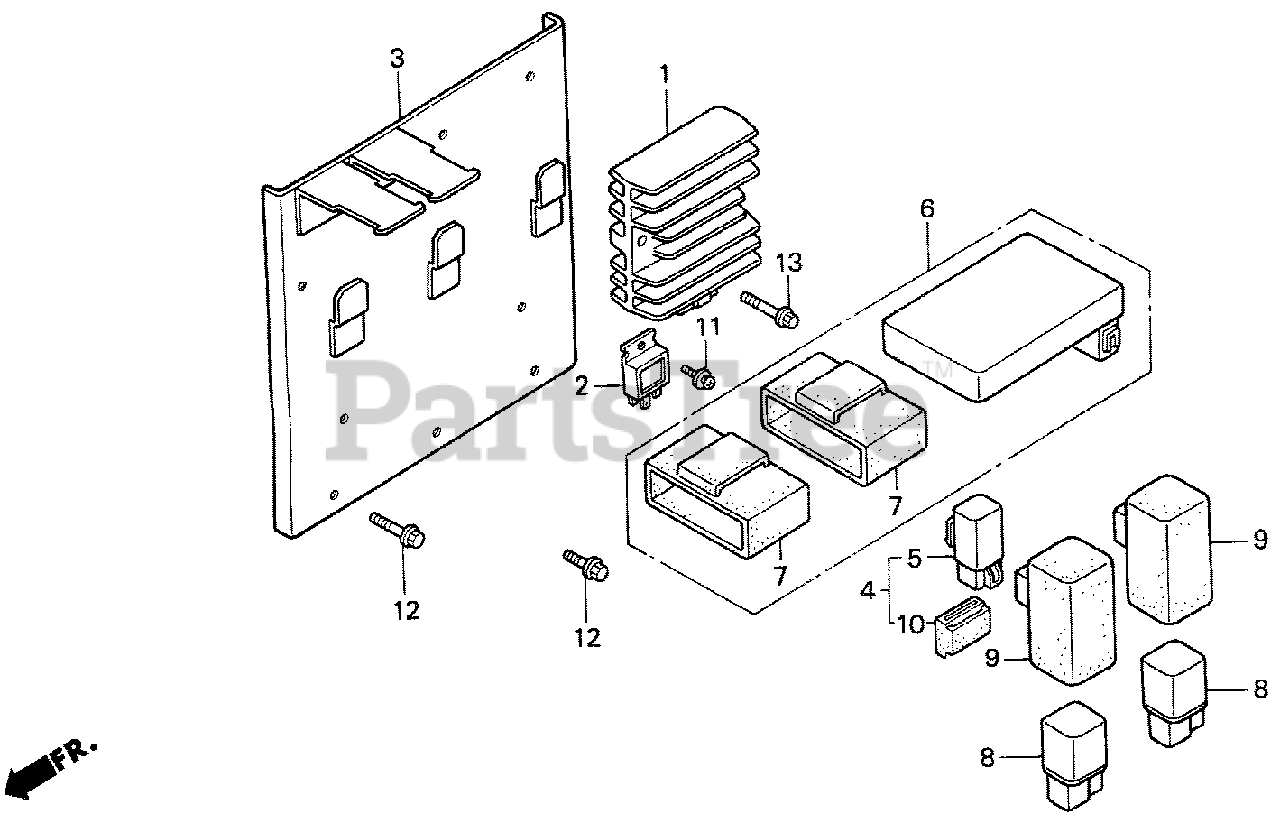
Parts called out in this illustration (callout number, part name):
1	RECTIFIER, REGULATOR
2	DIODE, D.C.
3	BRACKET, ELECTRIC PARTS
4	RELAY ASSY., CONTROL (20A)
5	RELAY (20A)
6	CONTROL UNIT ASSY., ENGINE
7	RUBBER, ENGINE CONTROL UNIT
8	RELAY, STARTER (OMRON)
9	SUSPENSION, STARTER RELAY (OMRON)
10	SUSPENSION, STARTER RELAY (TATEISHI)
11	SCREW-WASHER (5X12)
12	BOLT, FLANGE (6X12)
13	BOLT, FLANGE (6X25)
